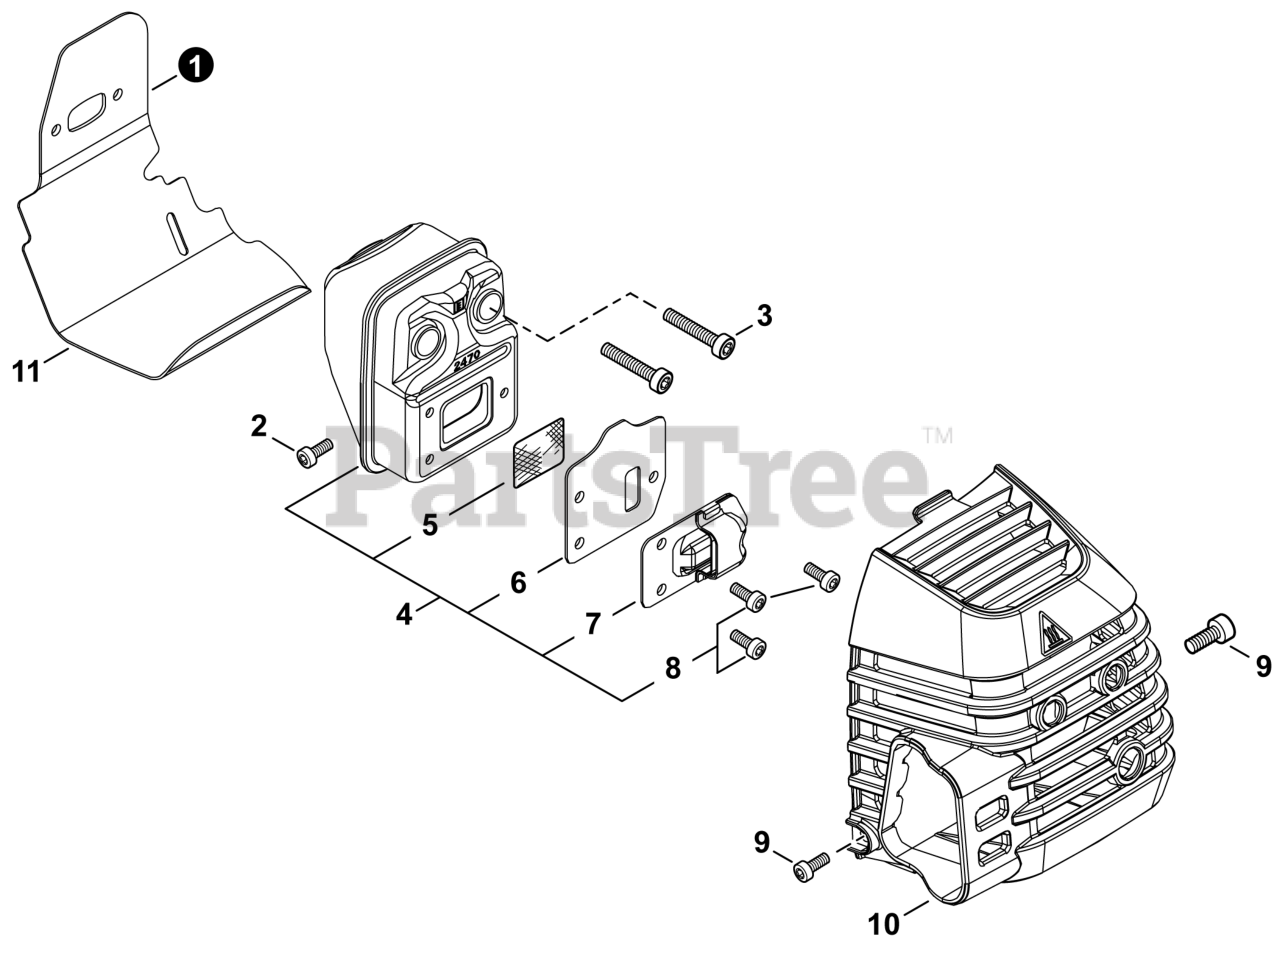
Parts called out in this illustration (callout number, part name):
1	HEAT SHIELD, EXHAUST
2	BOLT, TORX 5×12
3	BOLT, TORX 5×20
4	MUFFLER ASSY
5	SCREEN, SPARK ARRESTER
6	GASKET, EXHAUST
7	GUIDE, EXHAUST
8	BOLT, TORX 4×8
9	BOLT, TORX 5×12
10	COVER, MUFFLER
11	GASKET KIT
